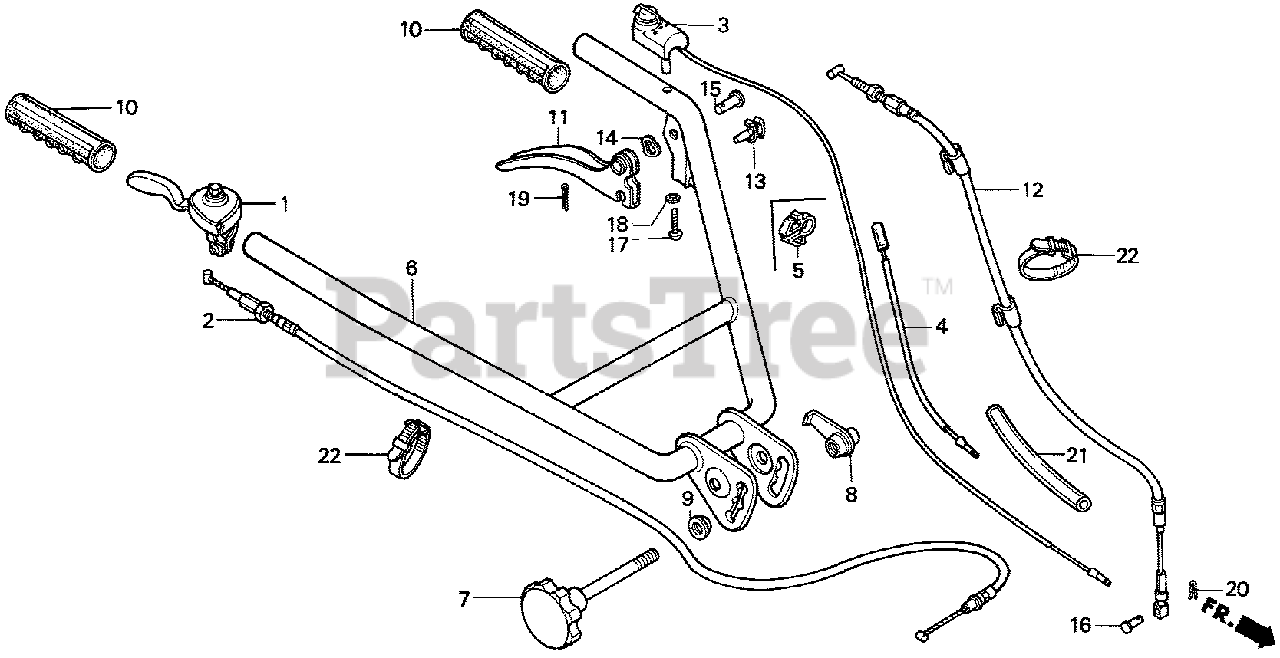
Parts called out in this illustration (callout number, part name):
1	LEVER ASSY., THROTTLE
2	CABLE, THROTTLE
3	SWITCH ASSY., ENGINE STOP (NOT AVAILABLE)
4	WIRE A, ENGINE STOP
5	HOLDER, STOP SWITCH WIRE
6	PIPE, HANDLE
7	ADJUSTER, HANDLE
8	NUT, HANDLE LOCK
9	NUT, SPECIAL (10MM)
10	GRIP, R. HANDLE
11	LEVER, CLUTCH
12	CABLE, CLUTCH (NOT AVAILABLE)
14	WASHER, WAVE (10MM)
15	PIN (8X18)
16	PIN (4X15.5) (NOT AVAILABLE)
17	SCREW, PAN (3X12)
18	WASHER, SPRING (3MM)
19	PIN, COTTER (2.0X15)
20	PIN, LOCK (4MM)
21	BULK HOSE, VINYL (12X16X3000) (12X16X130)
22	BAND B1, CABLE
